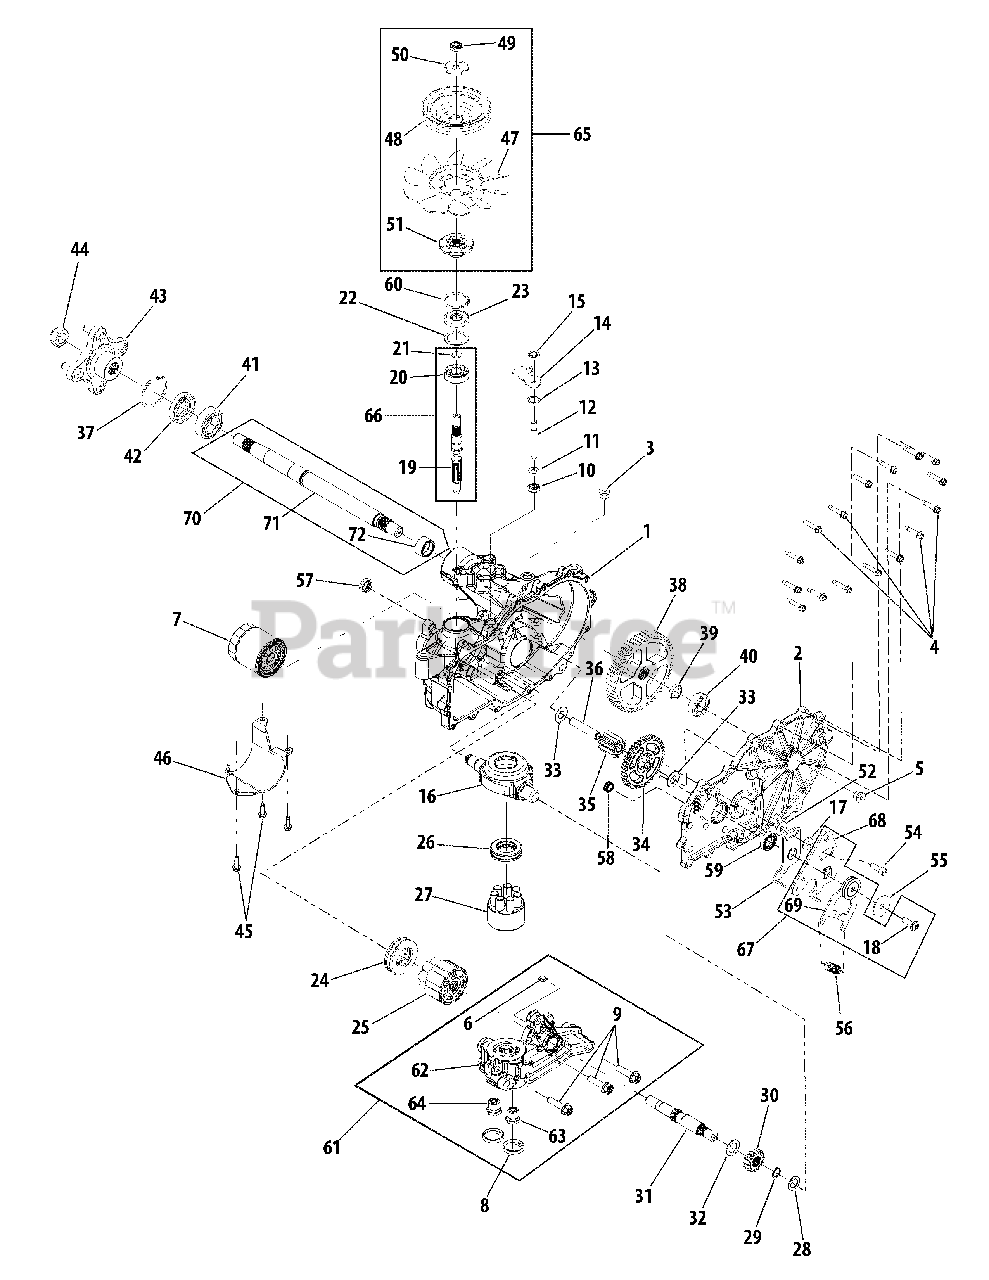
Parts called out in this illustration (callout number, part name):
1	Housing Assembly, Main
2	Side Cover Assembly
3	Plug, Straight Thread
4	Screw, Hex Flange
5	Plug, Straight Thread
6	Plate, Bypass
7	Filter, Oil
8	Seal, Plug
9	Screw, Hex Cap, 3/8-16 x 1.5 Patched
10	Seal, Lip
11	Ring, Retaining, .375 Ext.
12	Rod, Bypass
13	Ring, Retaining, .75 Int.
14	Arm, Bypass
15	Ring, Retaining, .375 Ext.
16	Swashplate, Trunnion
17	Washer, .34 x .88 x .06
18	Screw, Patch, 5/16-24 x 1
19	Shaft, Input
20	Bearing, Ball
21	Ring, Retaining
22	Washer, 1.23 x 1.56 x .04
23	Seal, Lip
24	Bearing, Thrust
25	Block Assembly, Cylinder
26	Bearing, Thrust
27	Block Assembly, 7 Piston
28	Washer, Flat, 5/8 x 1.0 x .05
29	Ring, Retaining
30	Gear, 16T
31	Shaft, Motor
32	Washer, .72 x 1.16 x .04
33	Washer, HT, .5 x 1.0 x .03
34	Gear, 43T
35	Gear, 11T
36	Pin, Jackshaft
37	Ring, Retaiining, 2.06 Int
38	Gear, 54T
39	Spacer, .75 x 1.0 x .257
40	Bearing, Ball
41	Bearing, Ball
42	Seal, Lip
43	Kit, Hub, 4 Bolt
44	Nut, Hex Lock, 3/4-16
45	Screw, Hex Cap, 1/4-20 x .75
46	Guard, Filter
47	Fan, 7"
48	Pulley Disc
49	Nut, Hex Lock, 1/2-20
50	Washer, Slotted
51	Hub
52	Spacer, .32 x 1.005 x .179
53	Arm, Neutral
54	Screw, Patch, 5/16-24 x 1
55	Washer, .343 x 1.5 x .062
56	Spring, Extension
58	Seal, Plug
61	Kit, Center Section
65	Kit, Fan/Pulley
66	Kit, Input Shaft
67	Kit, Return Bidirectional
70	Kit, Axle Shaft
